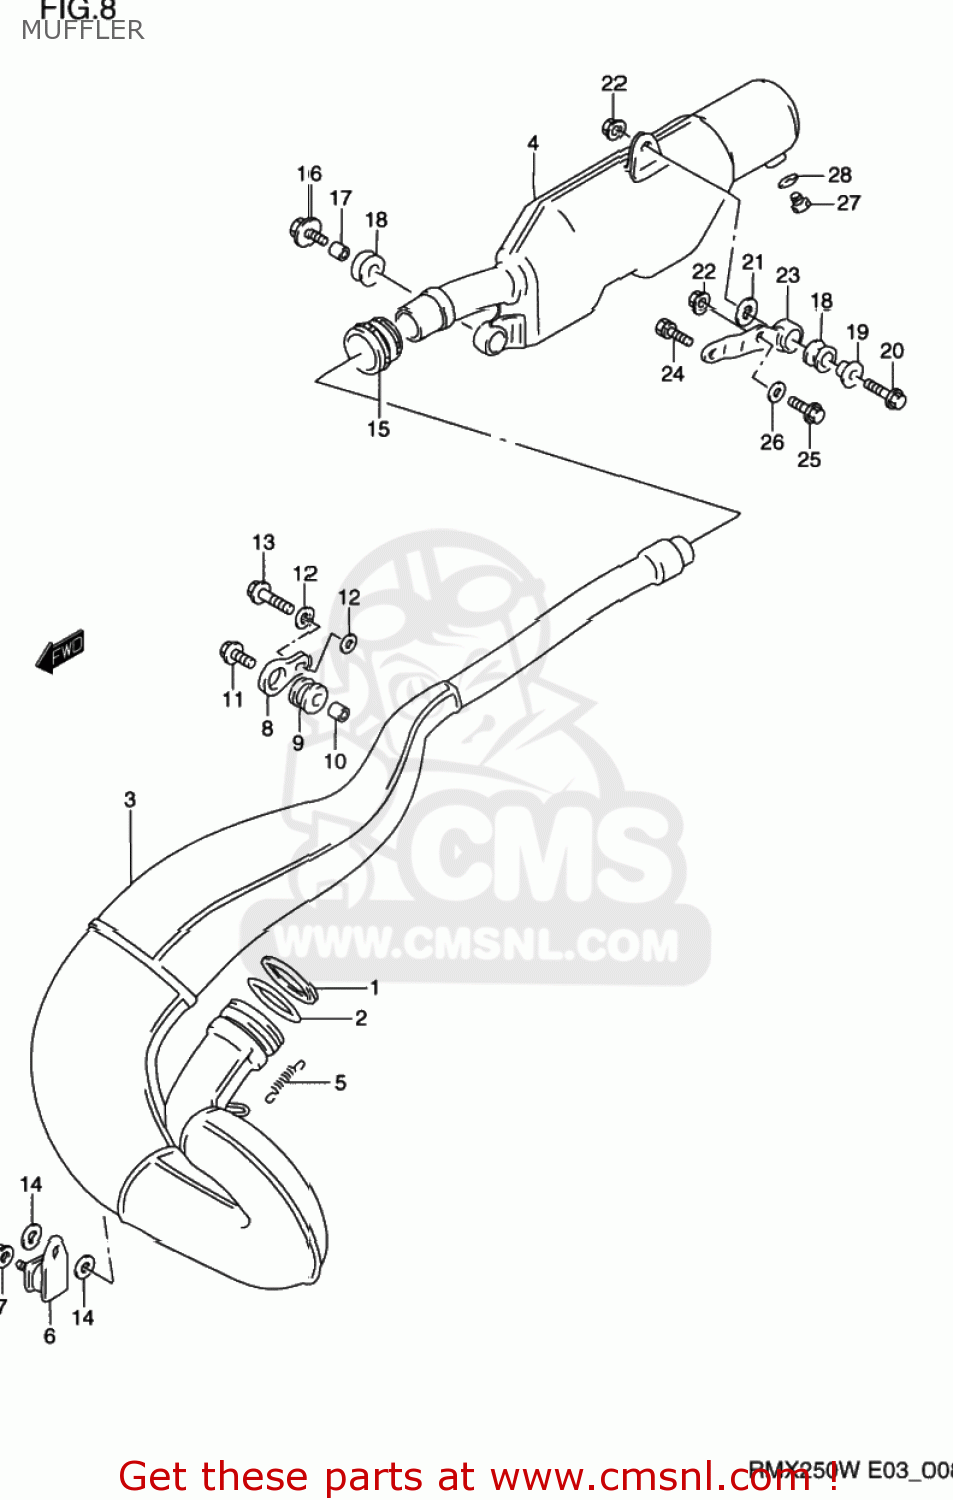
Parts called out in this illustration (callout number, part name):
1	WASHER,EXHAUST PIPE
2	O RING,EXHAUST PIPE
3	BODY,MUFFLER 1ST
4	BODY COMP,MUFFLER,SECOND
5	SPRING
6	DAMPER,MUFFLER SUPPORT
7	NUT
8	PLATE,MUFFLER MTG
9	CUSHION,MUFFLER
10	SPACER(6.5X9X13.5)
11	BOLT
12	WASHER (6.5X20X1.2)
13	SCREW
14	WASHER (8.5X19X2.3)
15	CONNECTOR,MUFFLER
16	BOLT(8X35)
17	SPACER(8.5X12X17.5)
18	CUSHION
19	SPACER(8.6X12X17.5)
20	BOLT
21	WASHER(8.5X28X1.6)
22	NUT
23	BRACKET COMP,MUFFLER SUPPORT
24	BOLT
25	BOLT
26	WASHER(8.5X20X1.6)
27	PLUG(12X9)
28	GASKET(12.1X16.2X3.7) (NAS)
